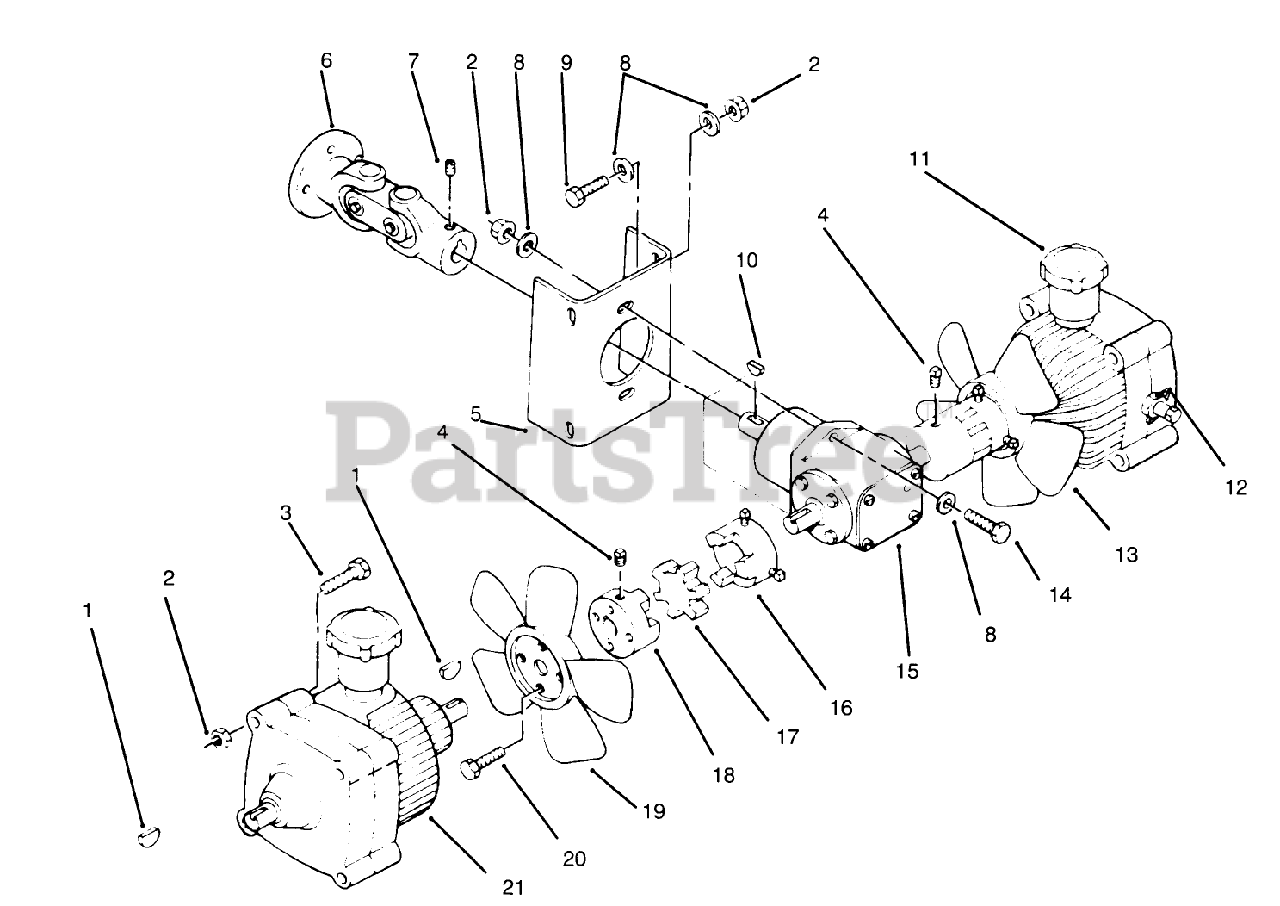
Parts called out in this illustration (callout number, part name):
1	KEY-HIPRO
2	NUT-LOCK, NI
3	SCREW-HH
4	1/2X1 CUP PT SETSCREW
5	BRACKET-GEAR BOX B
6	U-JOINT ASSY W/FLANGE
7	SCREW-SET
8	WASHER-FLAT
9	SCREW-HH
10	KEY-HI-PRO
11	TRANS-HYDRO CW
12	CLIP-DUMP VALVE
13	BLADE-FAN L.H.
14	SCREW-HH
15	GEAR BOX-T
16	COUPLING-KEYED
17	SPIDER-COUPLING
18	COUPLING-KEYED
19	BLADE-FAN R.H.
20	SCREW-TAPTITE
21	TRANS-HYDRO CCW.
